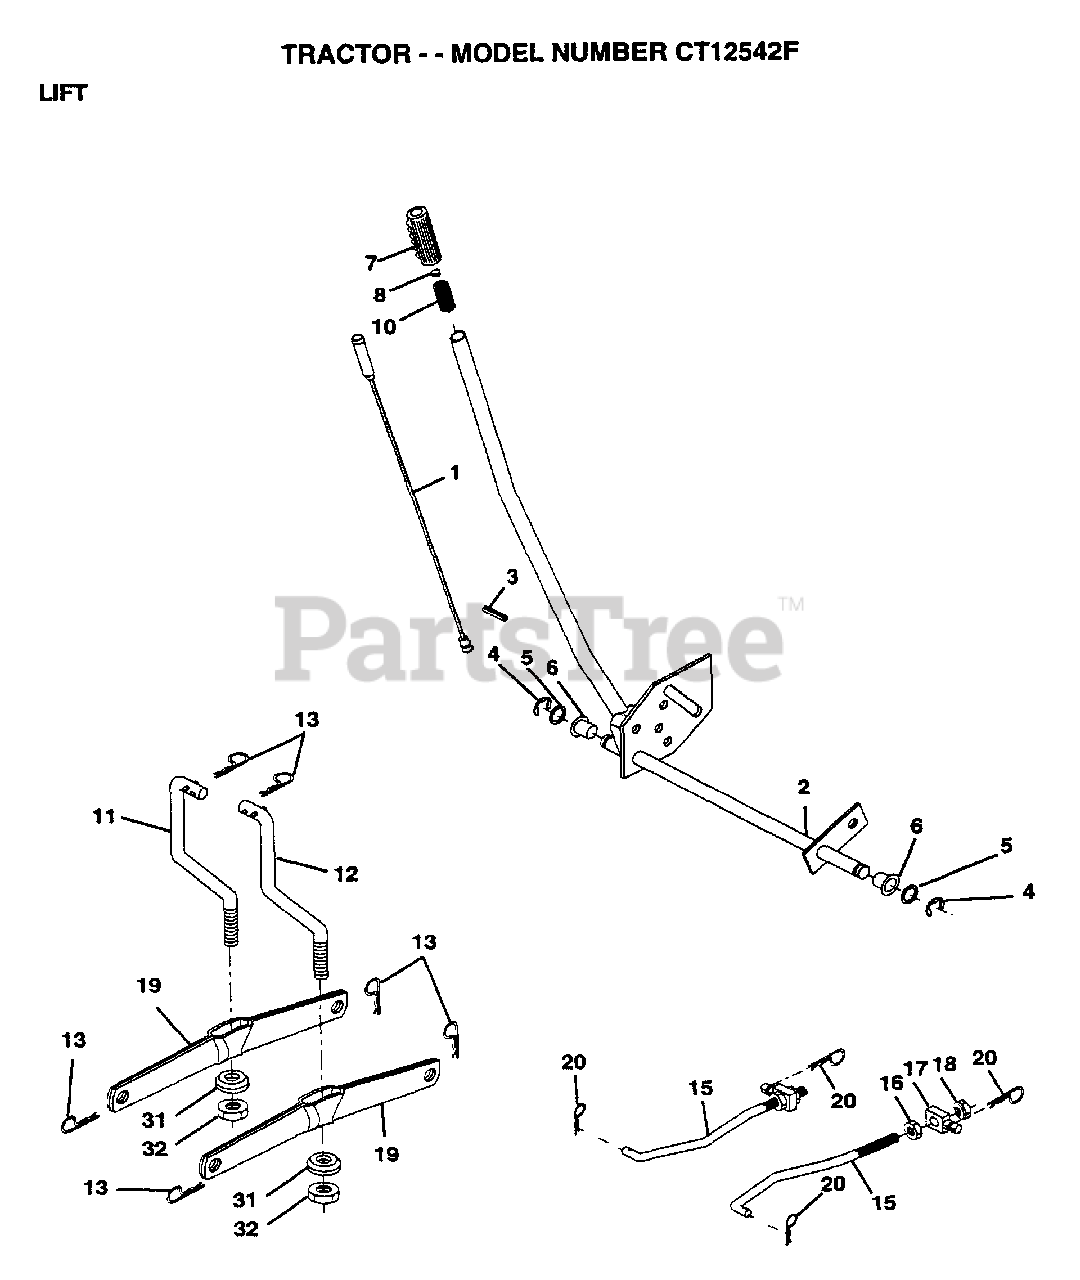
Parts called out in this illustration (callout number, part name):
1	WIRE ASM
2	HANDLE.LIFT.LH.
3	PIN GROOVE
5	WASHER
6	NYLON BEARING
7	GRIP
15	LINK.FRONT
16	NUT
17	TRUNION
18	NUT.LK.W/WSH.1/2.
19	ARM SUSP REAR
20	RETAINER.SPRING
31	BEARING PVT LH
32	NUT.CROWNLOCK.3/8
